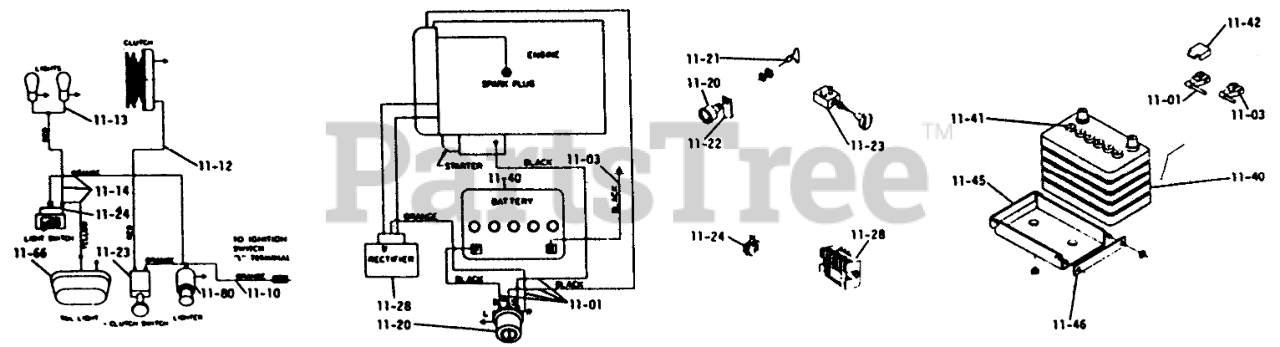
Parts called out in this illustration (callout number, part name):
11-10	ASSY FUSED CONN
11-12	Wire-Clutch to switch
11-20	SWITCH
11-46	LINK BATTERY CLAMP
